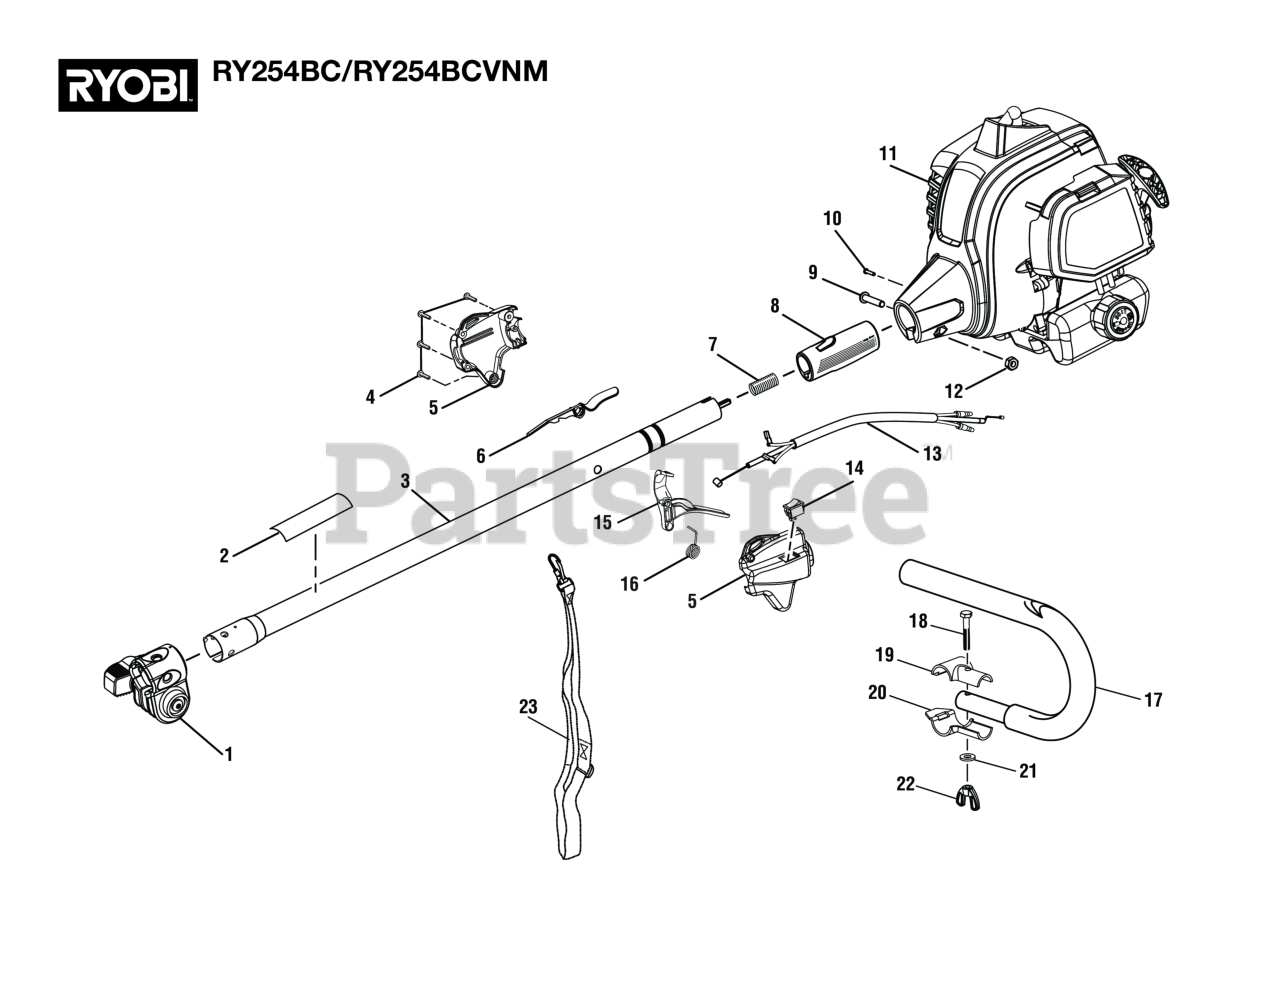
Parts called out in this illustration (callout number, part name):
1	Boom Clamp Assembly
2	Warning Icon Label
3	Upper Boom Assembly (Inc. Key Nos. 1-2)
4	Screw (M4 x 20 mm, T20 Torx Pan Hd. S.T.)
5	Control Handle Assembly (Inc. Key No. 6)
6	Trigger Lock
7	COMPRESSION SPRING
8	Rear Handle Grip
9	Screw (M6 x 30 mm, T27 Torx Button Hd.)
10	Screw (M4 x 8 mm, T25 Torx Pan Hd. T.F.)
11	Powerhead Assembly w/Labels
12	Hex Nut (M6.3 x 1)
13	Throttle Cable and Wire Assembly
14	Stop Switch (Momentary Contact)
16	Torsion Spring (Throttle Trigger)
17	"J" Handle and Grip
18	Bolt (1/4-20 x 1-1/2 in., Hex Hd.)
19	Top "J" Handle Clamp
20	Bottom "J" Handle Clamp
21	Washer (ID7.25 x OD16 x 1.5t)
22	Wing Nut (1/4-20, Plastic)
23	Shoulder Harness Assembly
